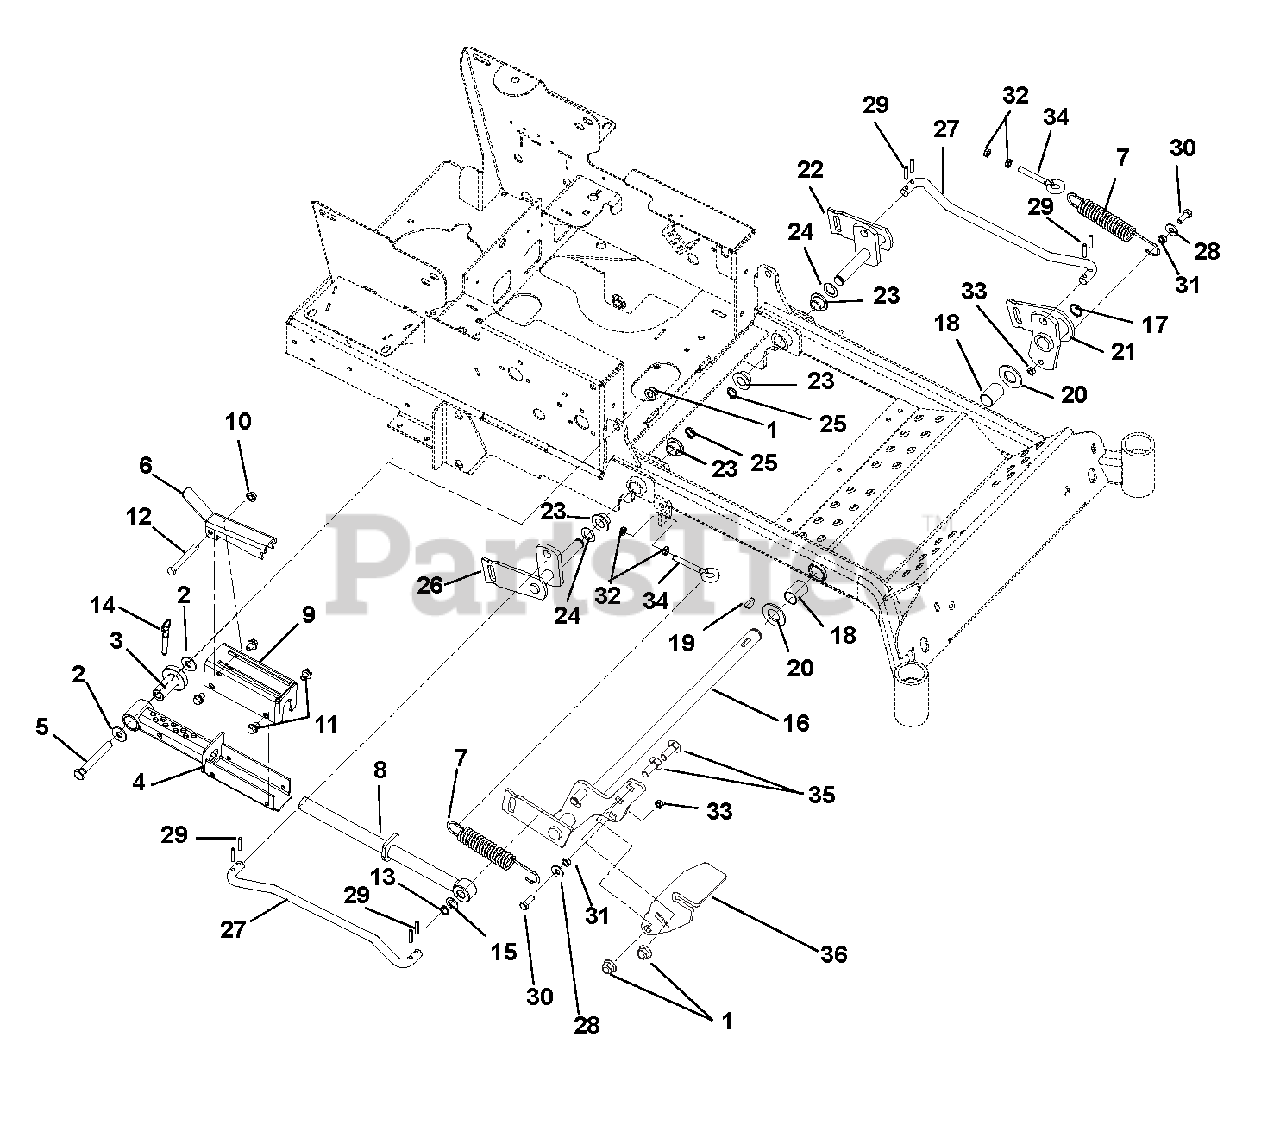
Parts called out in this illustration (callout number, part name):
1	@NUT-LK-NYL-FLG .50-13 YWZC
2	WSHR-FL-STL .531X1.250X.10 YWZ
3	BEARING, PEDESTAL
4	WMT, MECHANICAL LIFT
5	@BLT-HEX .50-13X3.75 GR5 YWZC
6	LOCK-UP, MECH LIFT
7	SG-TENS .162X1.25X8.25 WLD 25
8	WMT, MECH. LIFT SHAFT (.62)
9	WMT, MECH LIFT COVER
10	@NUT-LK-NYL-FLG .38-16 YWZC
11	@SCR-TAP .38-16X.50 HWH TR YWZ
12	@BLT-HEX .38-16X3.25 GR5 YWZC
13	RG-RTNG-EXT .625X.050
14	PIN, SPRING BALL .375OD X 1.50
15	WSHR-FL-STL .630X1.005X.062 YZ
16	WMT,DECK LIFT,ADJ FOOT PEDAL
17	RG-RTNG-EXT 1.00X.078
18	BSHG,1.00ID X 1.125OD X 1.50LG
19	KEY-WDRF .25X1.00 HRD #15
20	WSHR-FL-STL- 1.062X2.0X.134 YZ
21	WMT, LH FRONT MOWER LIFT
22	WMT, LH REAR LIFT ARM (100)
23	BSHG-FLG .762X1.0X.580X1.48 NY
24	WSHR-HDND-THRST .758X1.23X.031
25	RG-RTNG-EXT .689X.078
26	WMT, RH REAR LIFT ARM (100)
27	ROD-LIFT ASSIST 16.35"
28	@WSHR-FL-STL.438X1.00X.083 YWZ
29	PIN-ROLL .250X1.25 STNLESS STL
30	@BLT-HEX .38-16X1.00 GR5 YWZC
31	BSHG-SLV .377X.624X.235
32	NUT-HEX-JAM .375-16 YWZC
33	@NUT-LK-CTR-JAM .375-16 YWZC
34	BLT-EYE .375-16X2.50 YWZC
35	@BLT-RDHDSQNK .50-13X1.50 G5YZ
36	PEDAL, FOOT
